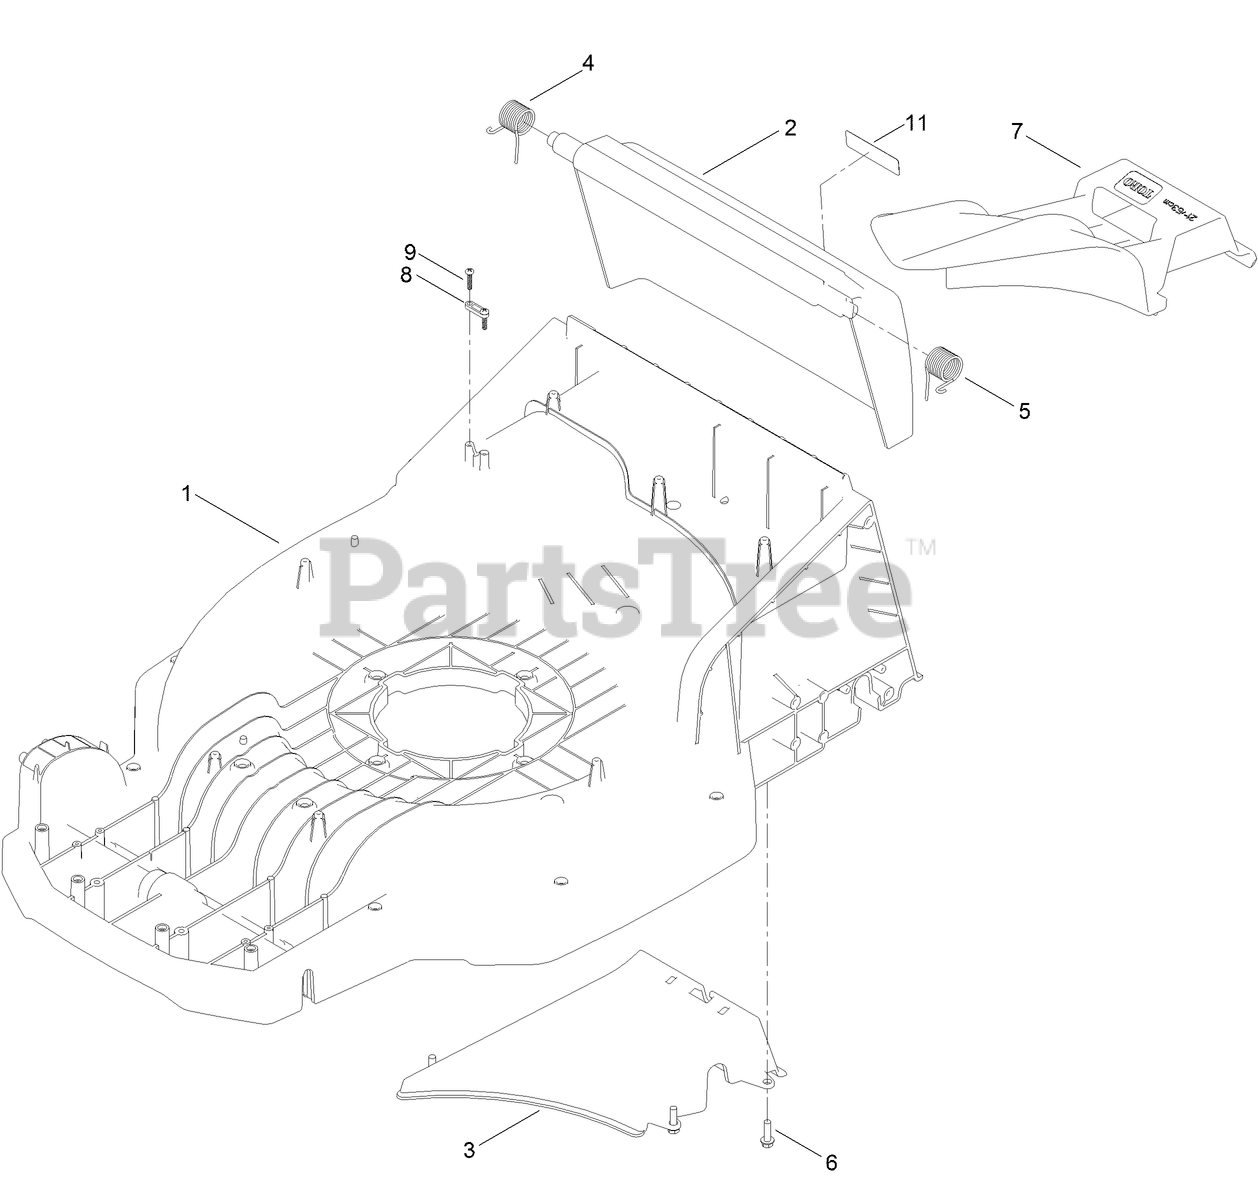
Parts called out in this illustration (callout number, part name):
1	DECK-PLASTIC, 21"
2	ASM-REAR DOOR, IN-MOLD (60V)
3	RAMP-DISCHARGE
4	SPRING-TORSION, RH
5	SPRING-TORSION, LH
6	SCREW-HWH
7	PLUG-DISCHARGE
8	CLAMP-HARNESS
9	SCREW-PPH
11	DECAL-PROP 65, SHORT, TRILINGUAL
